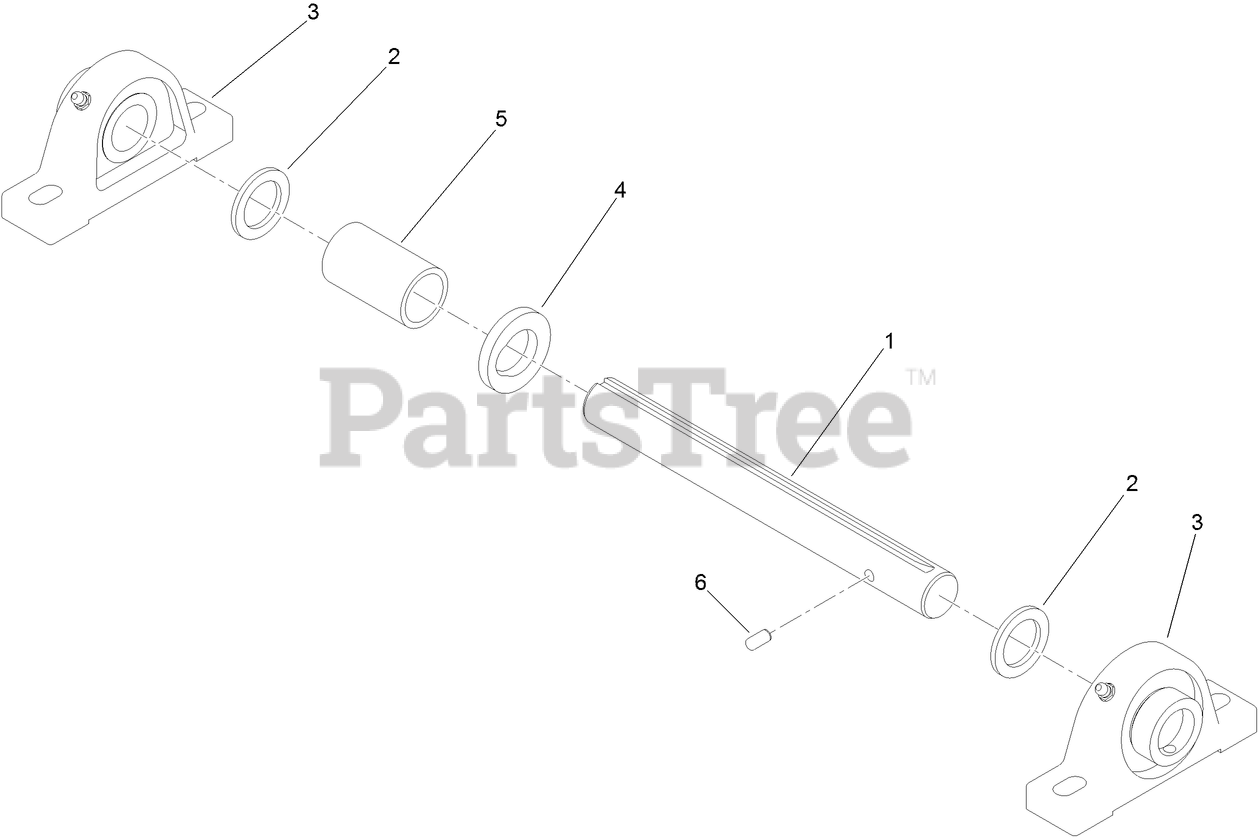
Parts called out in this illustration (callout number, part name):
2	WASHER-THRUST
3	BEARING-BLOCK, PILLOW
4	WASHER
5	SPACER-IDLER
6	PIN-DOWEL
